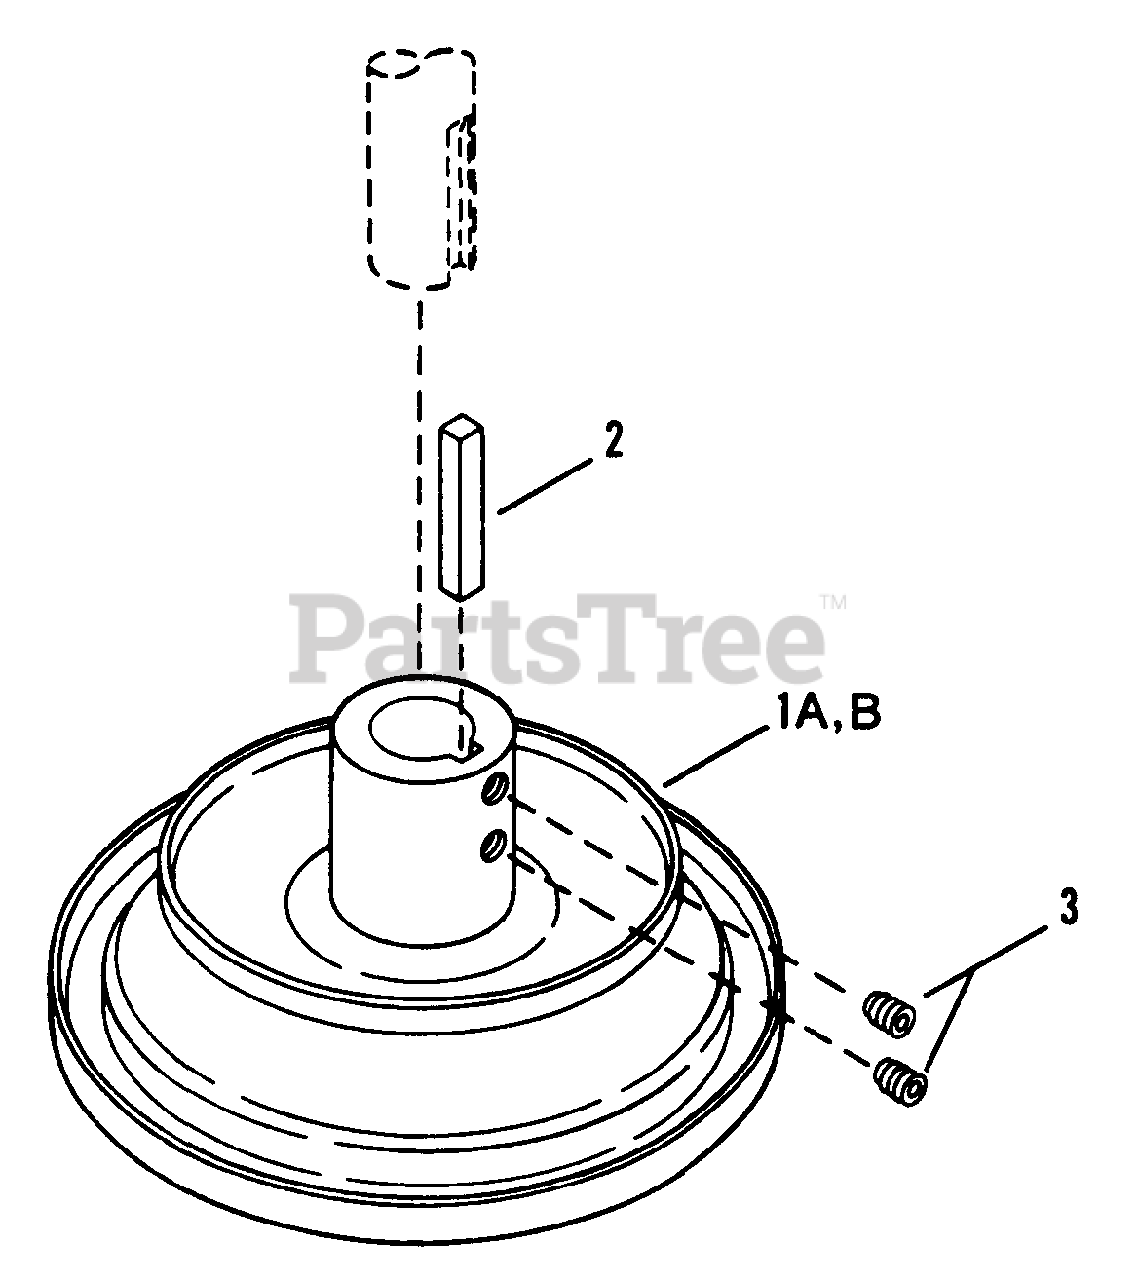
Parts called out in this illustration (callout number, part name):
1A	ASSEMBLY, Drive Disc, 4" O.D.
1B	ASSEMBLY, Drive Disc, 5" O.D.
2	KEY, 1/4 x 1/4 x 2"
3	SET-SCREW, 3/8 - 16 x 3/8"
